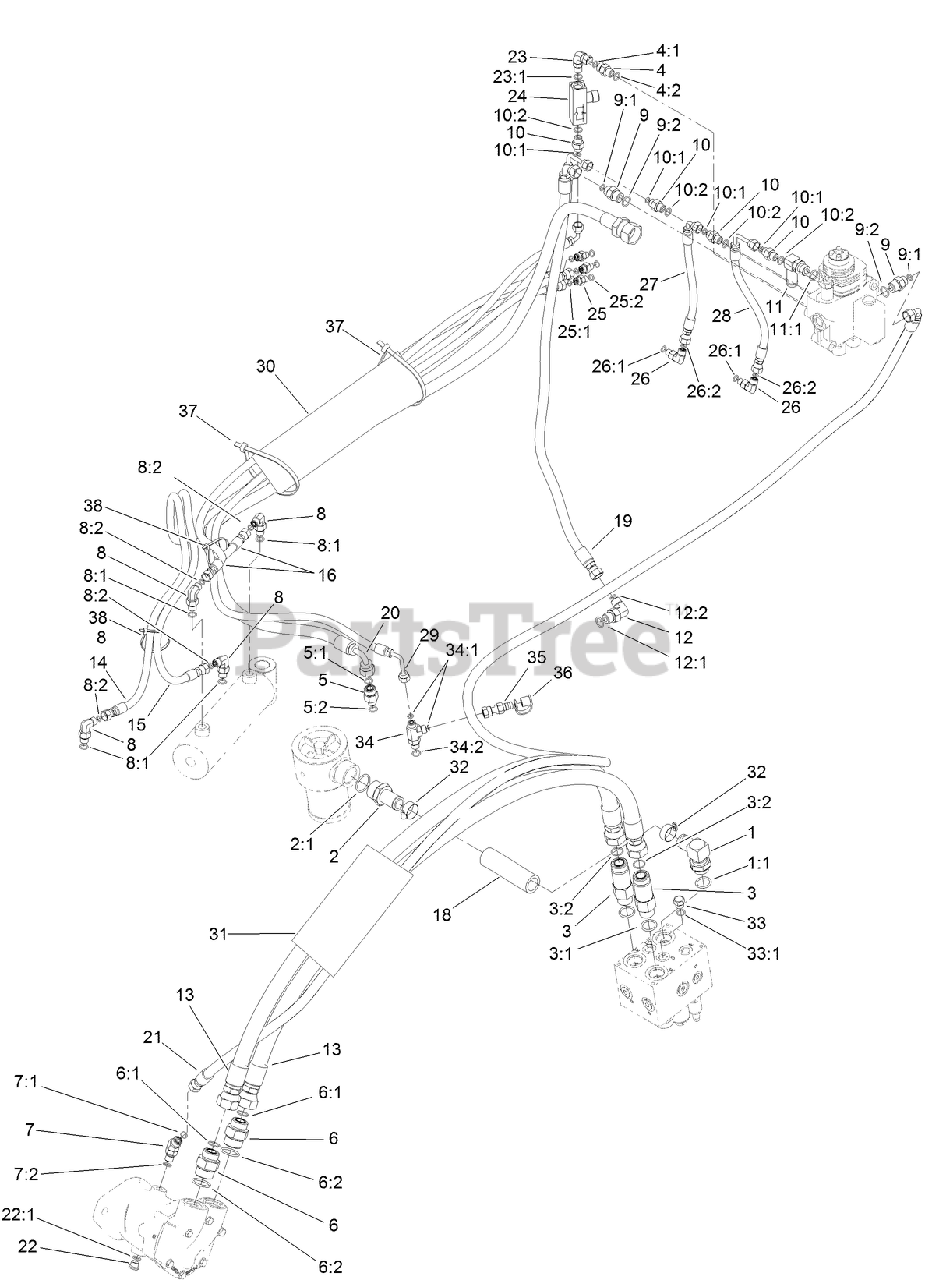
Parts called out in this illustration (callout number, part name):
1	FITTING-HYD, 90 DEG
1:1	O-RING
2	FITTING-STR
2:1	O-RING
3	FITTING-HYD
3:1	O-RING
3:2	O-RING
4	FITTING-STRAIGHT
4:1	O-RING
4:2	O-RING
5	FITTING-STR
5:1	O-RING
5:2	O-RING
6	FITTING-STR
6:1	O-RING
6:2	O-RING
7	FITTING-ELBOW-45
7:1	O-RING
7:2	O-RING
8	FITTING-ELBOW 90
8:1	O-RING
8:2	O-RING
9	FITTING-STRAIGHT
9:1	O-RING
9:2	O-RING
10	FITTING-STRAIGHT
10:1	O-RING
10:2	O-RING
11	FITTING-ELB 90
11:1	O-RING
12	FITTING-HYD, 90 DEG
12:1	O-RING
12:2	O-RING
13	HOSE-HYD
14	HOSE-HYD
15	HOSE-HYD
16	HOSE-HYD
18	HOSE-RETURN
19	HOSE-HYD
20	HOSE-HYD
21	HOSE-HYD
22	PLUG-HEX, HOLLOW
22:1	O-RING
23	FITTING-SWIVEL, 90 DEG
23:1	O-RING
24	VALVE-CONTROL, FLOW
25	FITTING-STRAIGHT
25:1	O-RING
25:2	O-RING
26	FITTING-90 DEG
26:1	O-RING
26:2	O-RING
27	HOSE-HYD
28	HOSE-HYD
29	HOSE-HYD
30	SLEEVE-PROTECTIVE
31	SLEEVE-PROTECTIVE
32	CLAMP-HOSE
33	PLUG-HH
33:1	O-RING
34	FITTING-TEE
34:1	O-RING
34:2	O-RING
35	NIPPLE-TEST
36	CAP-DUST
37	TIE-CABLE
38	TIE-CABLE
